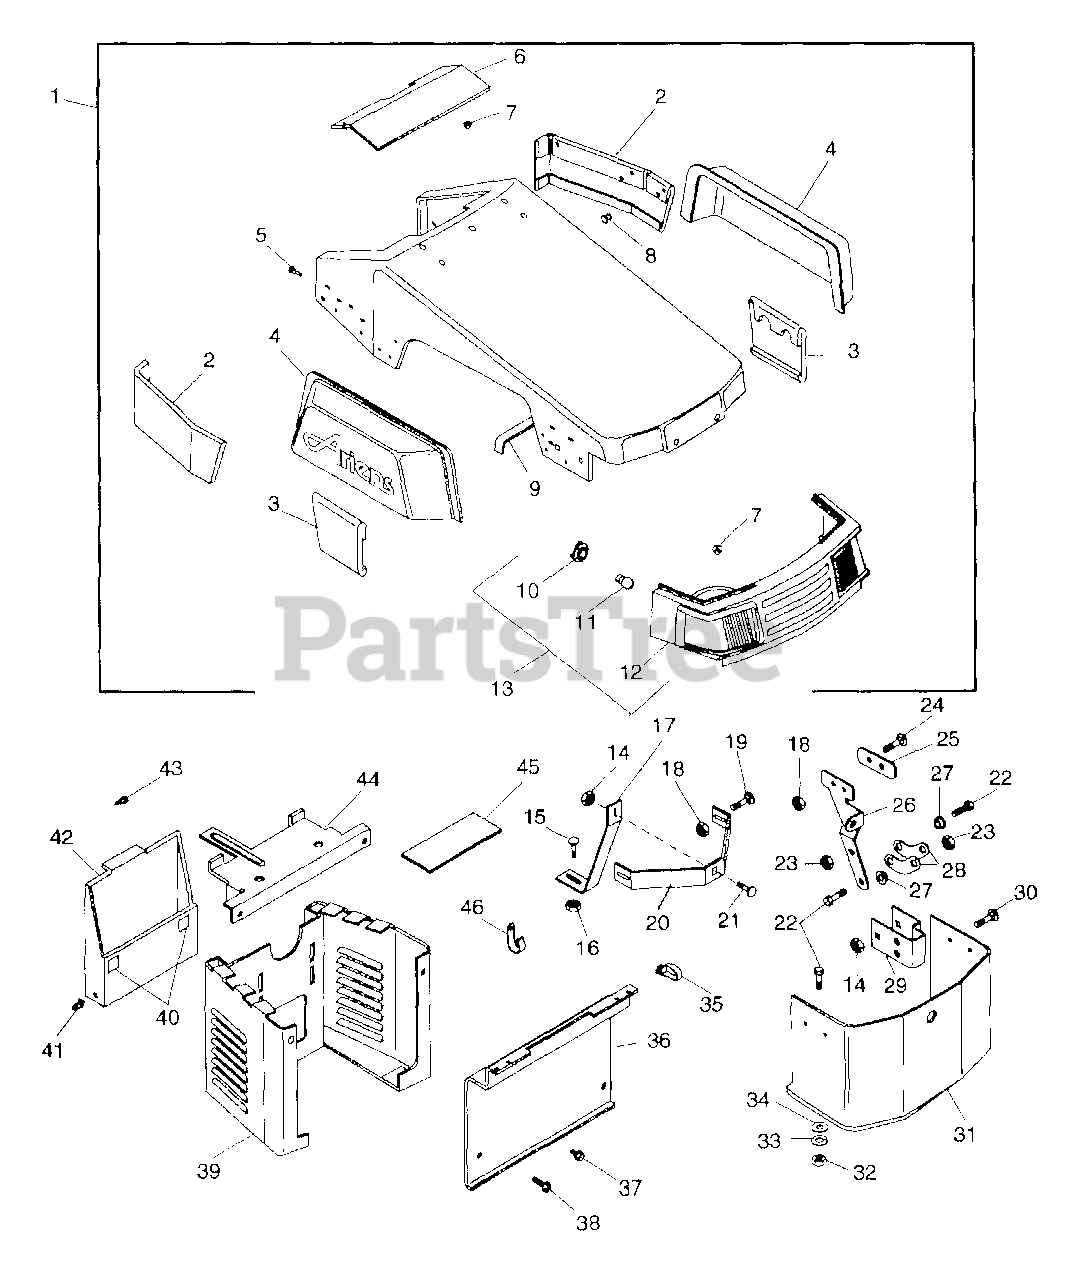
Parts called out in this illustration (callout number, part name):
1	HOOD ASSY HT 16-18 V-TWIN
2	REAR HOOD MOLDING R H
2	REAR HOOD MOLDING L H
3	FRONT HOOD MOLDING R H
3	FRONT HOOD MOLDING L H
4	ENGINE SHROUD
6	HAND HOLD TRIM
7	NUT-SELF-THRDNG FITS.25 STUDPL
8	RVT-BRIV .153 X .179 DOME AL
9	FOAM TAPE
10	LAMP SOCKET
11	HEADLIGHT BULB, 1156
12	GRILL & LENS ASSEMBLY
13	HEADLIGHT SYSTEM HT
14	NUT-LK-FLG .250-20 PL
15	BLT-RDHDSQNK .375-16X.75 GR5PL
16	NUT-LK-FLG .375-16 PL
18	NUT-FLG. .312-18 PL
19	BLT-RDHDSQNK .312-18X.62SHTPL
21	BLT-RDHDSQNK .25-20X.75 GR5PL
22	BLT-HEX .31-18X.75 PL GR2
23	NUT-LK .312-18 GR A PL
24	BLT-RDHDSQNK .31-18X.75 GR5 PL
25	SPACER STRAP
26	HINGE ARM R H
26	HINGE ARM L H
27	BSHG, FLG .325X.499X.26X.88
29	HINGE BRACKET
30	BLT-RDHDSQNK .25-20X.50 SHT PL
32	NUT-HEX .312-18
33	WSHR-LK .312X.097 PL HVY
34	WSHR-FL-STL .323X.625X.062 PL
35	CLIP-HARNESS TINNERMAN
36	BULKHEAD
37	SCR-TAP .312-18X.50 HWH PL TR
38	SCR-TAP 10-16X.50 HWH PL AB
39	DASH TOWER
40	CATCH ASSEMBLY
41	PLASTIC GROMMET
42	NOTE BOX
43	SCR-TAP 10-12X.50 CRPH PL A
44	BATTERY SUPPORT
45	FOAM TAPE
